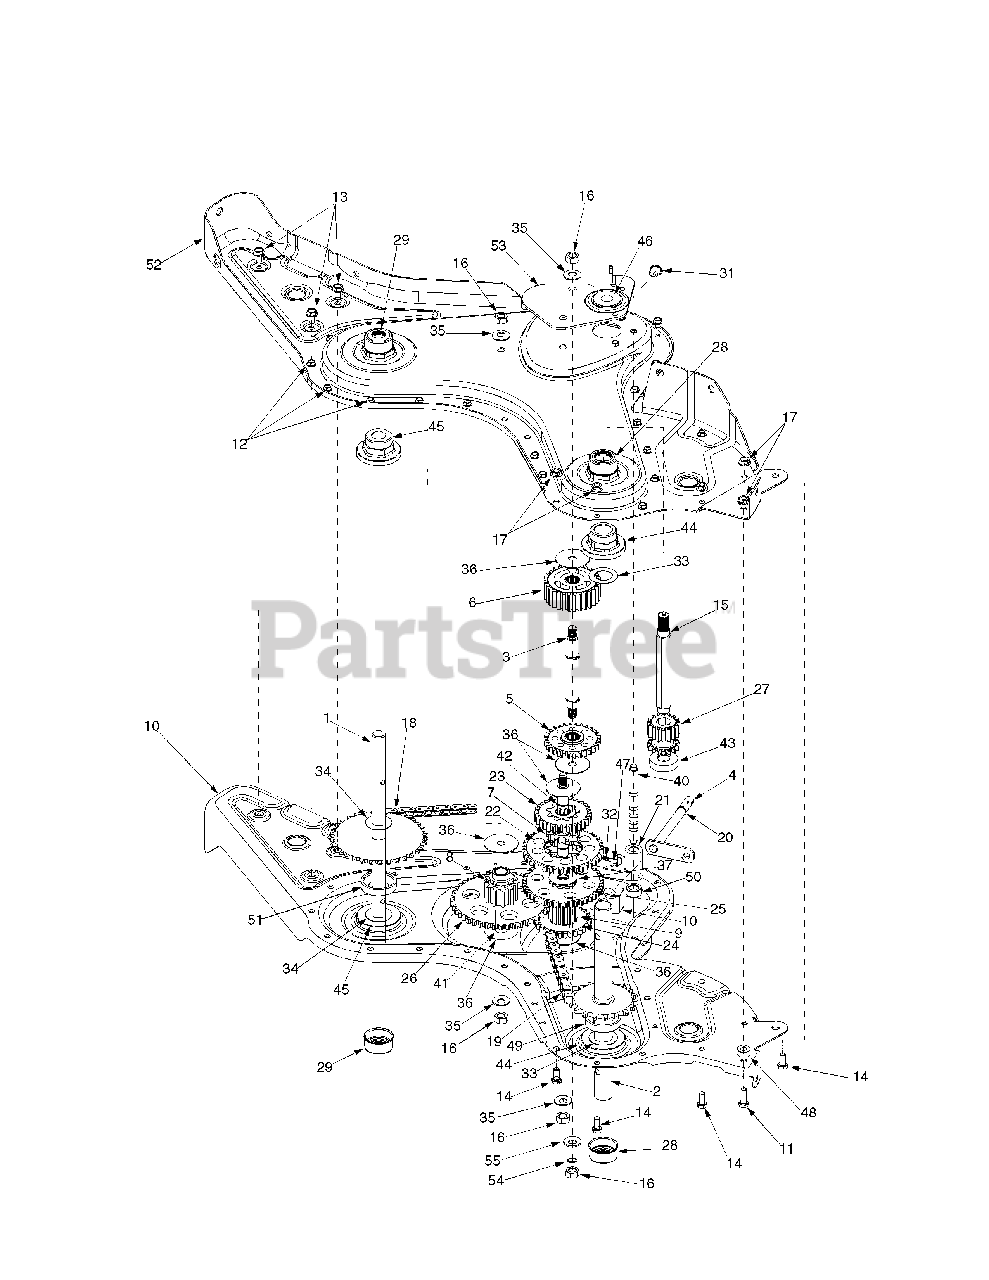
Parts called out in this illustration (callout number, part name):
1	Wheel Shaft Ass’y 33T
2	Tine Shaft Ass’y: 18T
3	Jack Shaft Ass’y
4	Input Shaft Ass’y
5	Rev Idler Gear Ass’y: 30T
6	Tine Idler Gear Ass’y: 30T
7	Tine Input Sprocket Ass’y: 9T
8	Wheel Input Sprocket Ass’y: 10T
9	Gear Ass’y: 11T
11	Hex Bolt 5/16-18 x 1" Lg
12	Hex S-Tap Scr 1/4- 20 x 5"
13	Hex S-Tap Scr 5/16-18 x 625"
14	Hex Bolt 5/16-18 x 75"
15	Input Shaft
16	Hex Nut 7/16-20
17	Flange Nut 5/16-18
18	#420 Chain 1/2 Pitch x 50 Links
19	#50 Chain 5/8 Pitch x 54 Links
20	Snap Ring
21	Shifting Fork
22	Spur Gear 44T
23	Spur Gear 30T
24	Spur Gear 30T
25	Spur Gear 44T
26	Spur Gear 44T
27	Spur Gear 16T
28	Seal 1 0 Shaft
29	Seal 75 Shaft
31	Taper Cap Ring
32	Compression Spring 50" Leg
33	Thrust Wash 1 03" I D X 1 62"
34	Fl-Wash 76" I D x 1 5" O D
35	Bell-Wash 45" I D x 1 0"
36	Thrust Wash 445 x 1 92 x 060
37	Fl-Wash 635" I D x 1 59 O D
40	Detent Shaft 1/2" Dia
41	Jack Shaft 625 x 2 385
42	Jack Shaft 625 x 5 0
43	Ball Bearing
44	Flange Bearing 1 0 x 2 5 x 1 38
45	Flange Bearing 75 x 2 5 x 1 38
46	Ball Bearing 6692 x 5745 x 466
47	Detent Ball 250
48	Spacer 315
49	Spacer 1 0 I D x 2 0 O D x 440
50	Spacer 505 I D x 88 O D x 440
51	Spacer 75 x 2 0 x 50
53	Gear Positioner Bracket
54	Lock Washer 7/16 Reg Duty
55	Flat Washer 474 x 879 x 064
